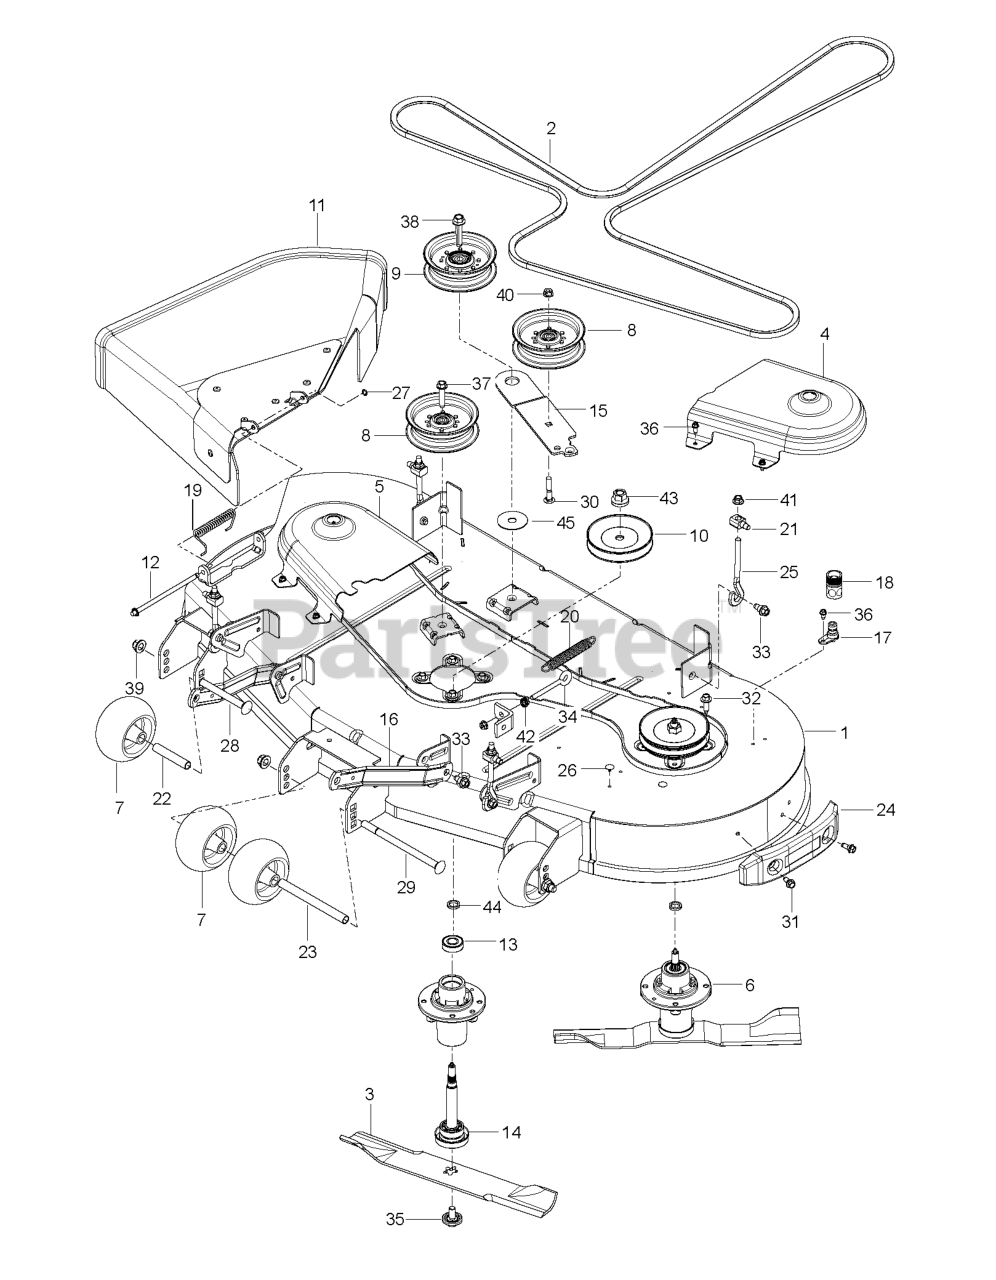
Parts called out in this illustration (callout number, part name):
1	DECK.SVC.54.CLRCT.MZ.MS668
2	BELT CLEARCUT 54, MZ DECK DRIV
3	BLADE CC54 PZ STYLE HIGH LIFT,
4	COVER 54 CLEARCUT, LH MANDREL,
5	COVER 54 CLEARCUT RH MANDREL O
6	MANDREL.DECK.ASSEMBLY
7	ROLLER, GAUGE .635 BORN
8	PULLEY.IDLER.2006
9	RB PULLEY.IDLER.4.50/HUB SPEC
10	PULLEY.MANDREL.CRD 107CM.DOM.
11	DEFLECTOR ASSY 54 CLEARCUT RES
12	ROD.HINGE
14	SHAFT ASM MANDREL
15	ARM IDLER ARM, CLEARCUT 54 BLA
16	ARM.RFIXED.MOWER.SUSPNSIONX431
17	PORT.WASHOUT
18	COUPLING.QUICK CONNECT
19	SPRING.42.FCS.DEFLECTOR
20	SPRING.MOWER.DRIVE.ELECTRIC
22	TUBE, ROLLER AXLE
23	TUBE, ROLLER AXLE LONG
24	BUMPER ASSY 54 CLEARCUT TRIM S
25	LINK.ADJUSTABLE
26	PLUG CHRISTMAS TREE
27	NUT PUSH M
28	RHSNB 1/2-13 X 4.75 GR5 ZD
29	RHSNB 1/2-13 X 8 GR5 ZD
30	BOLT
31	SHOULDER BOLT 5/16-18TT
32	BOLT.HEX.WASHR.HED.313-18X1.19
33	BOLT.SHOULDER
34	EYE BOLT 5/16 X 3.50
35	BOLT.WASHER.ASM.7/16-2
36	SCREW.1/4-20X5/8
37	SCREW LT
38	SCREW.7/16-14 X 2.125.WASHER
39	NUT, 1/2-13 HEX FLG NYLOC ZD
40	NUT LOCK FLG 3/8-16 UNC
41	NUT.FLANGE.LOCK
42	NUT 5/16C WHIZ
43	NUT.FLANGE.LOCK.TOP
44	WASHER.SPACER.MANDREL
